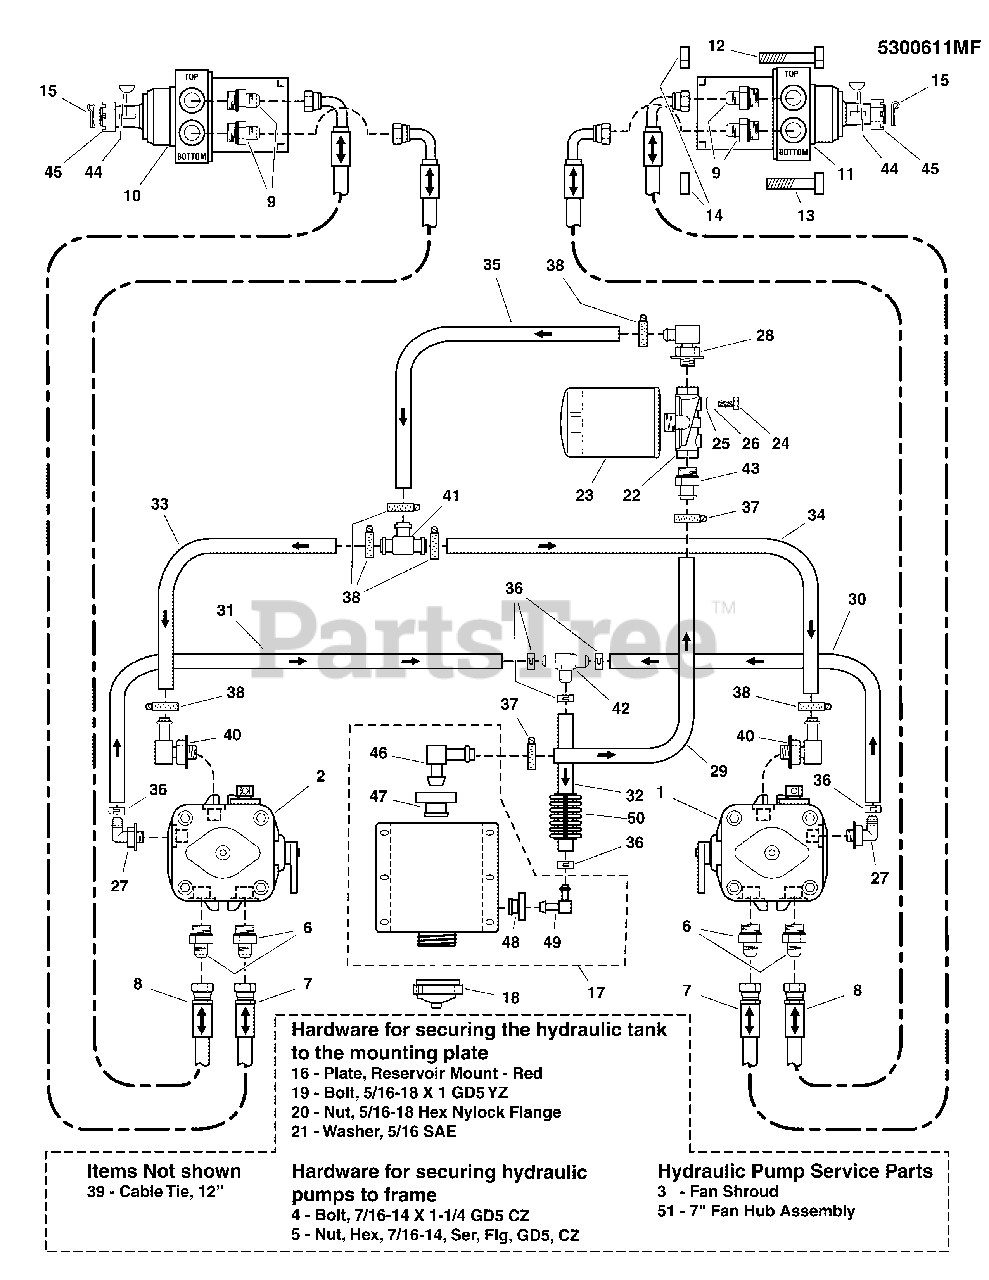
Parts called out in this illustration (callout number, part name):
1	PUMP, 16CC, PR-2KBQ-GV1F-XXXX
2	PUMP, 16CC, PR-2HBQ-GV1F-XXXX
4	BOLT, 7/16-14 X 1-1/4 GD5 YZ
5	NUT, Hex Flange, Whiz Lock 7/16-14
6	FITTING, Hydraulic, O-Ring Adapter
7	HOSE ASSEMBLY (33)
8	HOSE ASSEMBLY (29)
9	FITTING, Hydraulic, O-Ring Adapter
10	WHEEL MOTOR, LH, 17.1 CI
11	WHEEL MOTOR, RH, 17.1 CI
12	BOLT, 1/2-13 X 2-1/2, NYLON PATCH
13	BOLT, 1/2-13 X 2-1/4 PATCH
14	NUT, 1/2-13 SQUARE
15	PIN, COTTER, 1/8" X 1-1/4"
16	PLATE, RESERVOIR MOUNT - RED
17	HYDRAULIC OIL RESERVOIR, Complete (Includes Ref No. 3 - 6)
18	CAP, HYDRAULIC, SHIELDED VENT
19	CAPSCREW, Hex Head, 5/16-18 X 1
20	NUT, Ny Lock Flange, 5/16-18
21	WASHER, 5/16
22	FILTER HEAD, HYDRAULIC
23	FILTER, OIL
24	CAPSCREW, Hex Head, 1/4-20 x 3/4 (stiffener to top of cover)
25	WASHER, 1/4, Flat, GR5 Zinc/Clear
26	LOCKWASHER, 1/4, Black
27	ADAPTER, 90 DEG. 9/16 - 3/8 BARB
28	FITTING, 9/16 O-Ring, 1/2" HOSE, 90 DEG
29	HOSE, 5/8, PUSH-LOCK, 22.00
30	HOSE, 3/8" PUSH-LOCK, 22.00"
31	HOSE, 3/8" PUSH-LOCK, 30"
32	HOSE, 3/8" PUSH-LOCK, 30"
33	HOSE, 1/2" PUSH-ON, 28.00"
34	HOSE, 1/2" PUSH-ON, 13.00"
35	HOSE, 1/2" PUSH-ON, 7.00"
36	CLAMP, HOSE
37	CLAMP, #10 HOSE, STAINLESS
38	CLAMP, #6 HOSE, STAINLESS
39	TIE, SELF-LOCKING, 12"
40	FITTING, EXTRA LG, 90, 1/2 TUBE - 3/4-16
41	FITTING, BEADED TEE, 1/2 X 1/2 X 1/2, YZ
42	FITTING, TEE, 1/2" HOSE
43	FITTING, STRAIGHT, HYD #12618
45	NUT, CASTLE, 1-20 (SV)
46	FITTING, ELBOW, 5/8 (SV)
47	GROMMET (SV)
48	BUSHING
49	FITTING, ELBOW, 3/8 (SV)
50	WIRE LOOM, 5/8 ID, 6" LONG
51	7" FAN HUB ASSEMBLY, HYDROGEAR #70811
